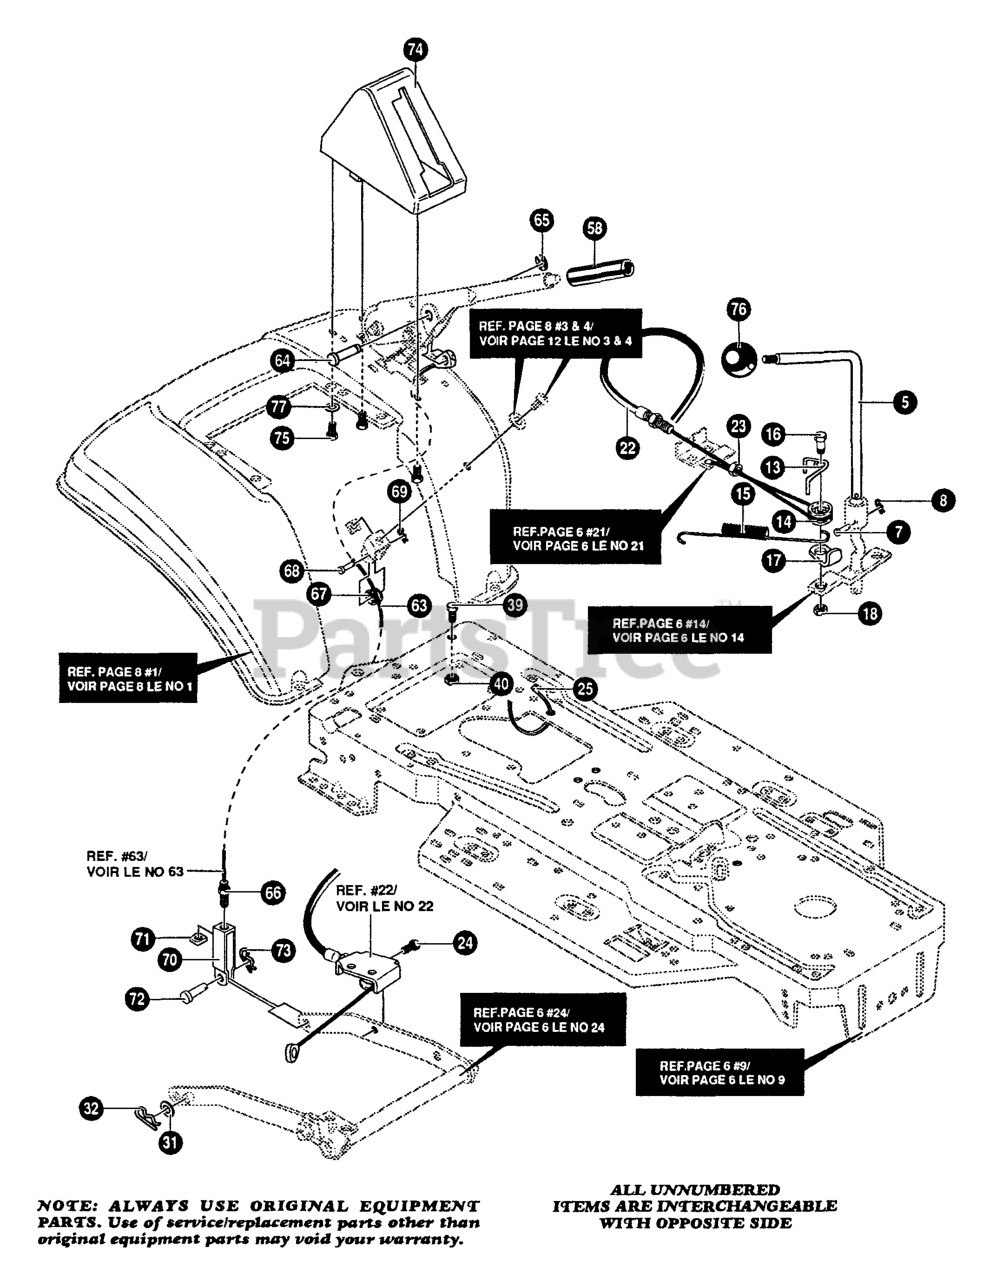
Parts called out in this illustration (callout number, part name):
5	LEVER, PTO UPPER
7	PIN, CLEVIS
8	PIN, HAIR
13	SPRING, CABLE KEEPER
17	BRKT, CABLE
22	ASSY, CABLE ENG
24	SCREW
25	TIE, CABLE
32	PIN, HAIR
39	SCREW
63	ASSY, CABLE LIFT
64	PIN, CLEVIS
65	RING, RET E
68	PIN, CLEVIS
69	PIN, HAIR
70	CLEVIS LIFT CABLE
72	PIN, CLEVIS
73	PIN, COTTER
74	LIFT COVER
77	WASHER
